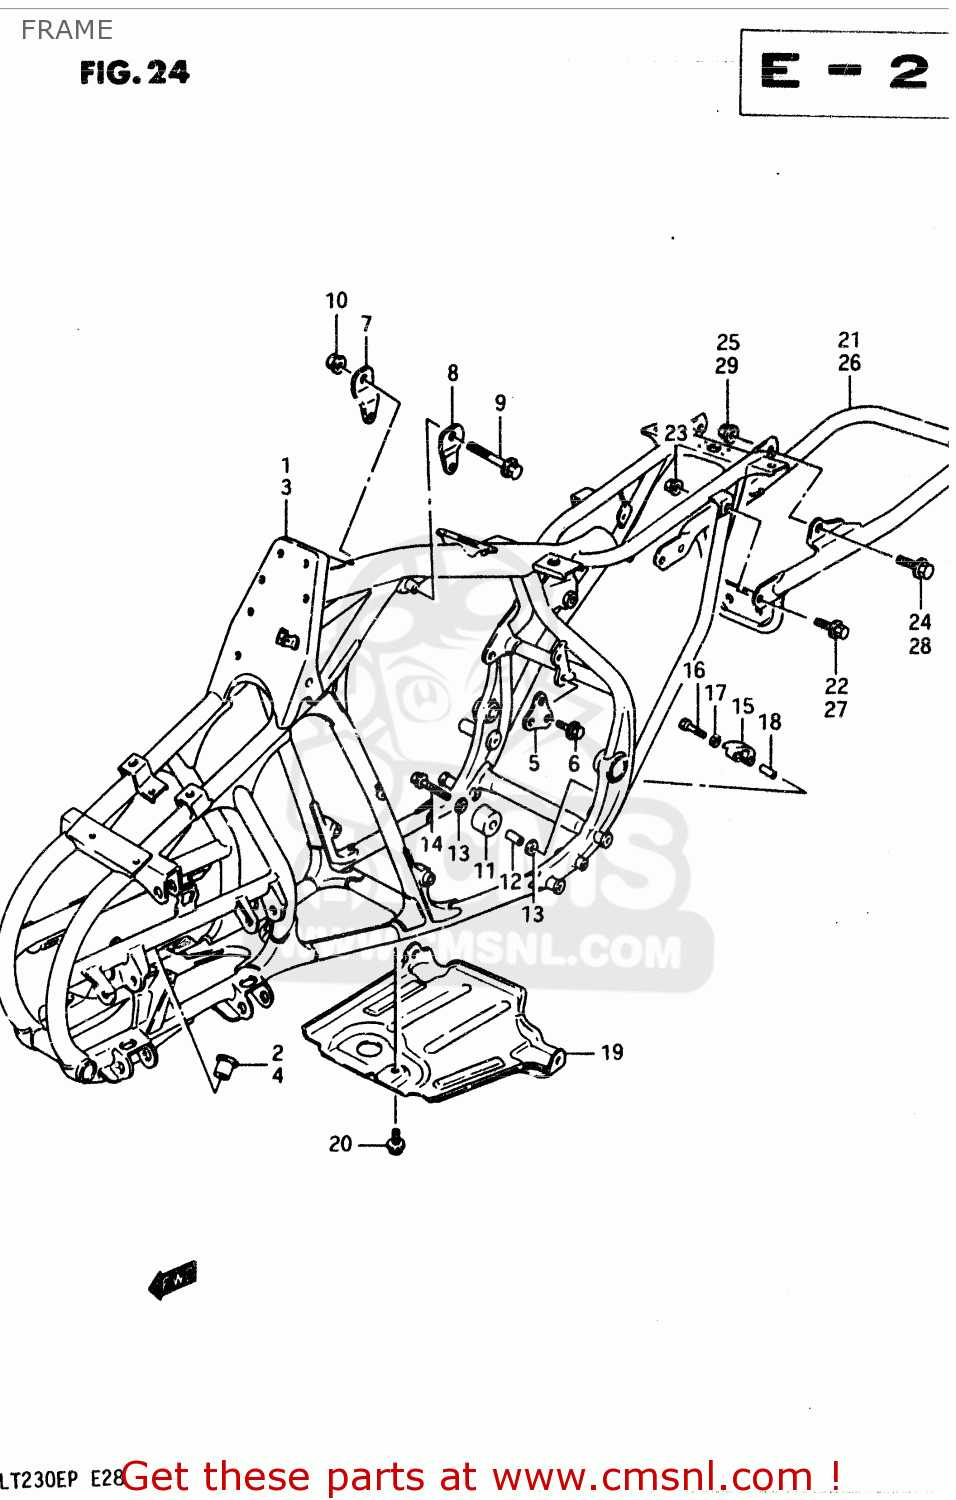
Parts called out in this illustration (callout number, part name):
1	FRAME (BLACK)
2	BUSH,STEERING SHAFT LWR
3	FRAME
4	BUSH
5	PLATE,ENGINE MOUNTING
6	BOLT
7	PLATE,ENG MTG UPR,R
8	PLATE,ENGINE MOUNTING
9	BOLT 10X75
10	NUT 10MM
11	ROLLER,CHAIN CONTROL
12	SPACER(8.6X12X25.5)
13	WASHER
14	BOLT(8X45)
15	BUFFER,CHAIN
16	BOLT
17	WASHER (6.3X14X1.6)
18	SPACER
19	PROTECTOR,ENGINE
20	BOLT
21	GRIP,REAR
22	BOLT
23	NUT
24	BOLT
25	NUT
26	GRIP COMP,REAR
27	BOLT
28	BOLT
29	NUT 10MM
